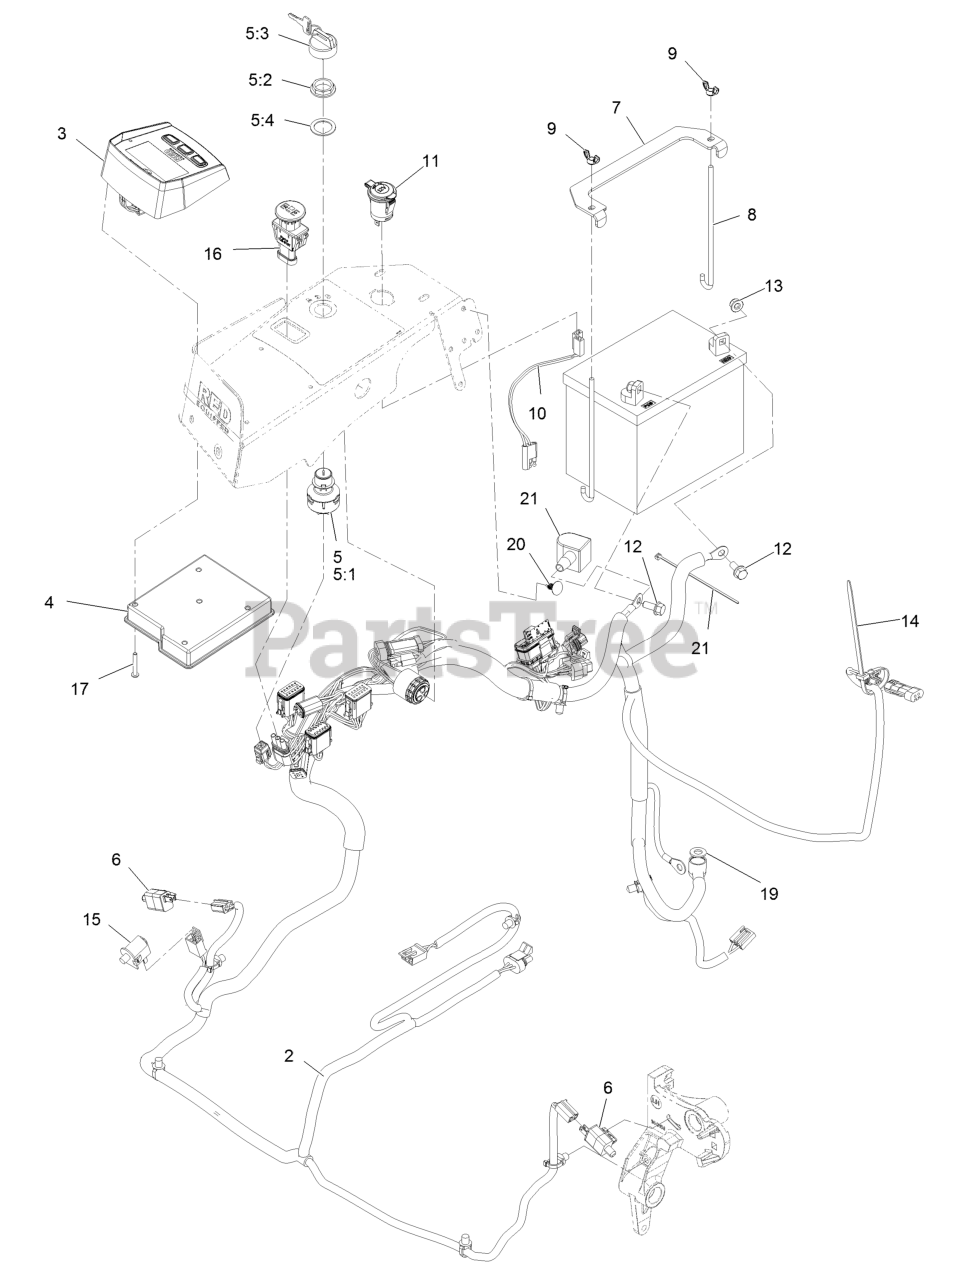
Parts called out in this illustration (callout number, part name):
2	Harness-Wire
3	Module, Ldu
4	Module-Mcu
5	Ignition Switch ASM
5:1	Switch-Ignition
5:2	Nut-Mounting
5:3	Ignition Key Set
5:4	Washer-Backup
7	Strap-Tie Down, Battery
8	Bolt-Holddown
9	Wingnut-Nyloc 1/4-20
10	Harness-Receptacle, 12V
11	Port-Power, 12V
12	Screw-HH Flg 5/16-18 X 3/4
13	Nut-Nyloc 5/16-18 Flg
14	Tie-Cable 7 15/16 (Large)
16	Switch-PTO, Sealed
17	Screw-PPH
19	Washer-3/8 SAE
20	Plug-Plastic
21	Tie-Cable
